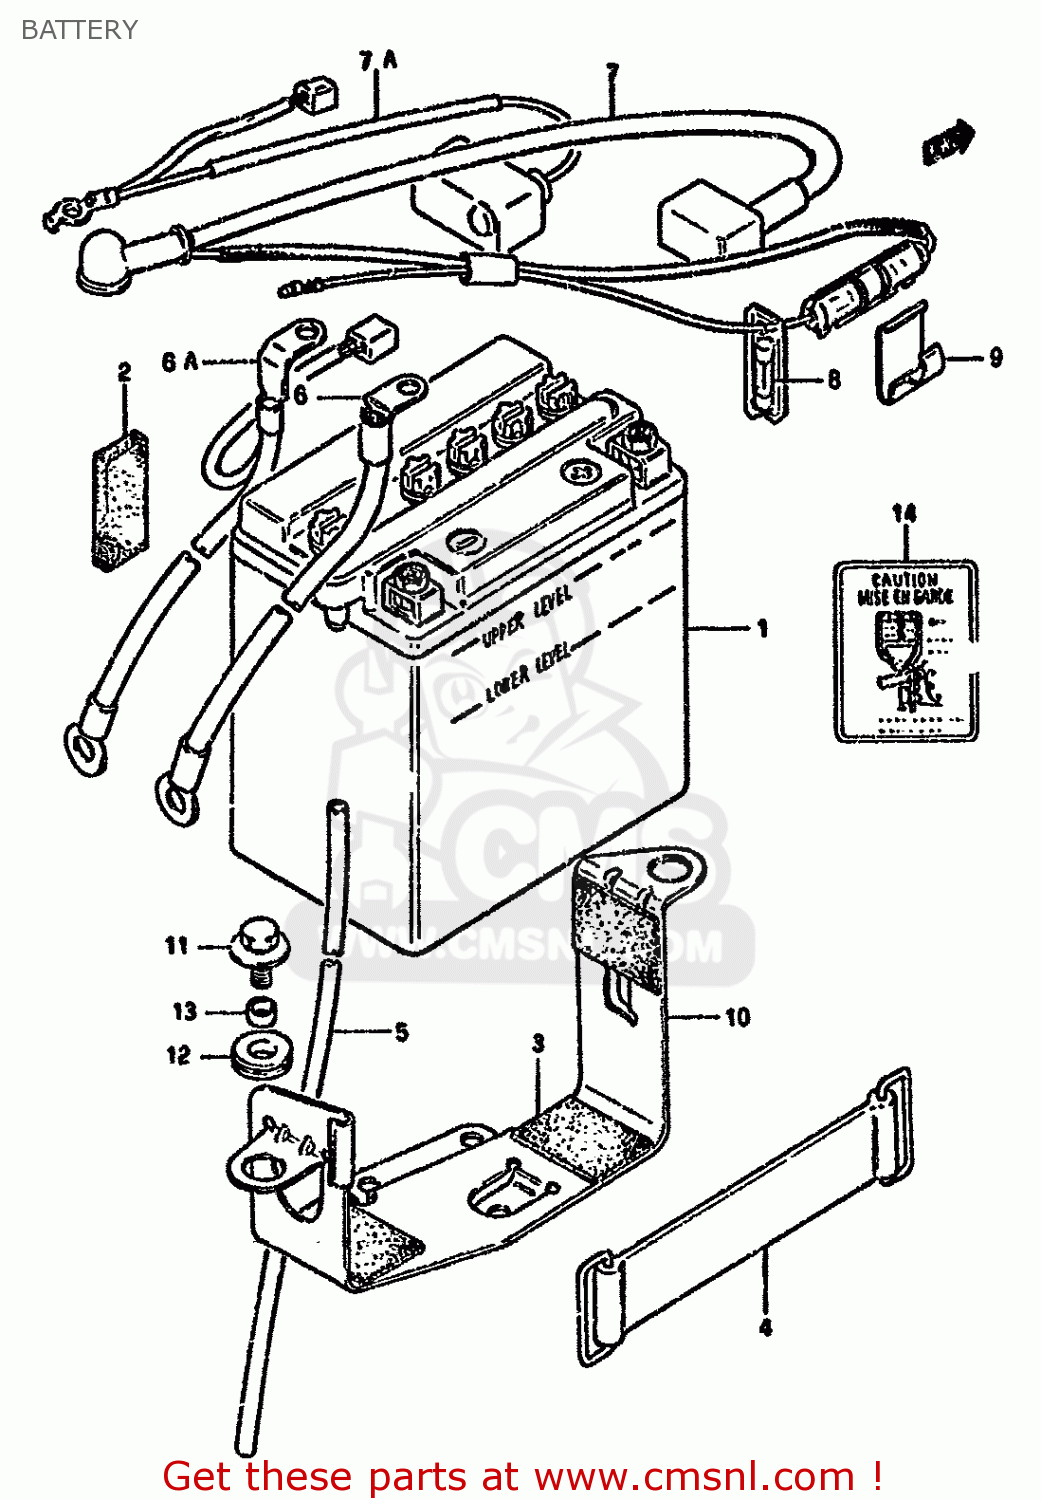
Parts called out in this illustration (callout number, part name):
1	BATTERY ASSY (12V)
2	PROTECTOR(170X95X3.0)
3	PROTECTOR(170X95X3.0)
4	BAND
5	HOSE,BATTERY EXHAUST
6	LEAD WIRE,BATTERY(-)
6A	WIRE,BATT.LEAD
7	CASE ASSEMBLY,FUSE (WITH
7A	WIRE, BATTERY (+) LEAD
8	FUSE(15A)
9	HOLDER,FUSE CASE
10	HOLDER,BATTERY
11	BOLT 6X16
12	CUSHION
13	SPACER(6.1X9X7.5)
14	PLATE,BATTERY CAUTION
